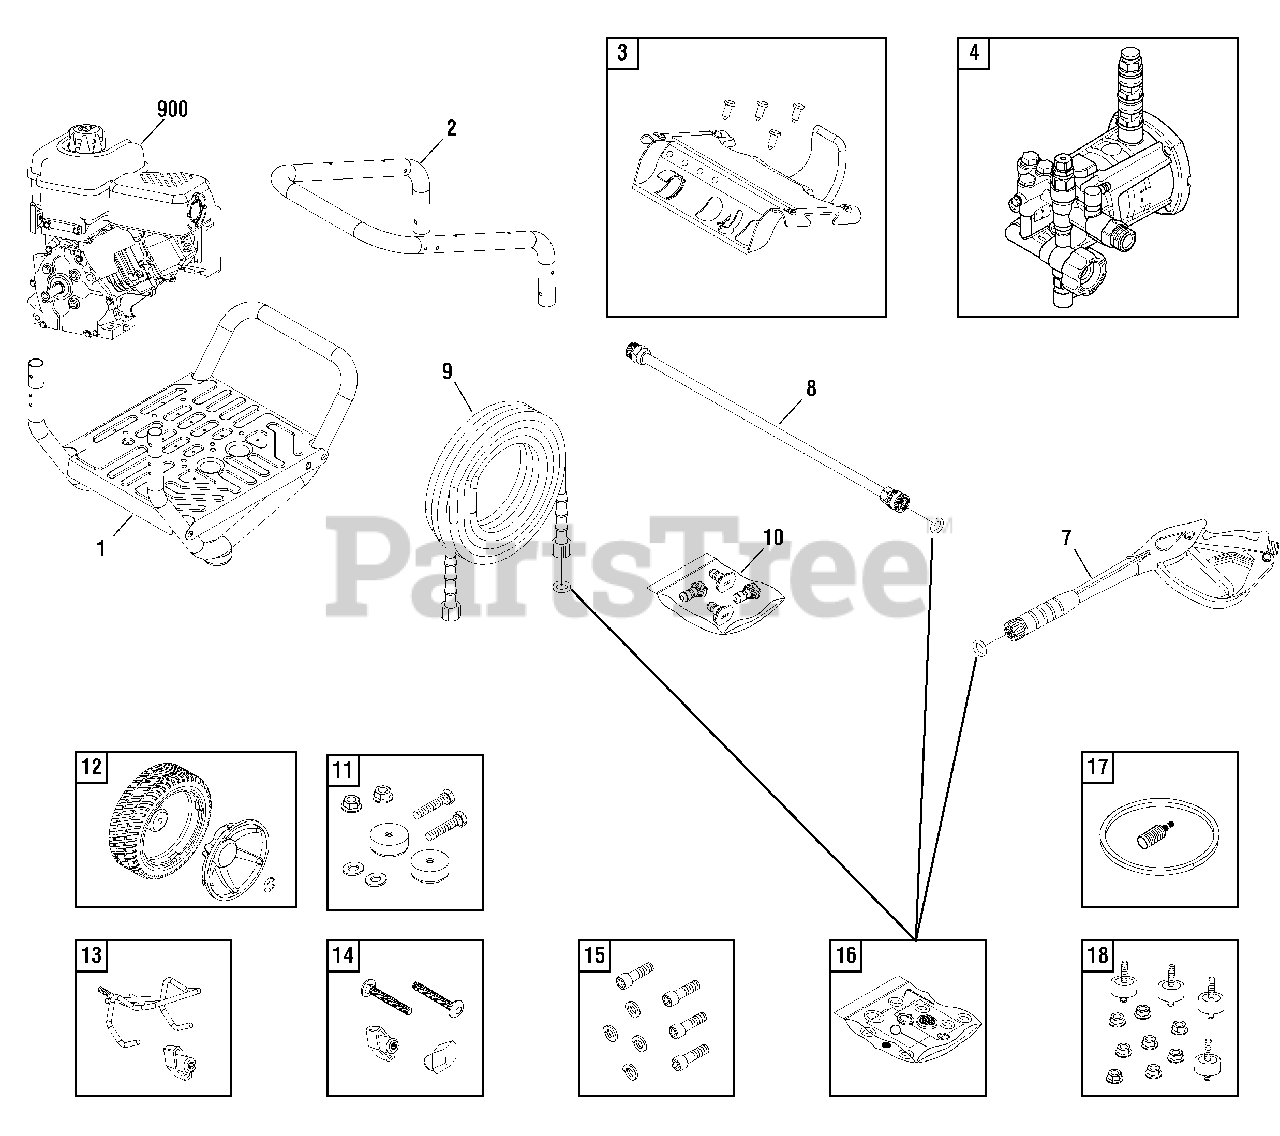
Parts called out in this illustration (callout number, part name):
8	EXTENSION-QC
10	KIT-QC NOZZLES
11	MOUNT-VIBRATION
14	KIT-HARDWARE, HANDLE
15	KIT-HARDWARE, PUMP MOUNTING
18	KIT- VIBRATION MOUNT
900	* ENGINE
